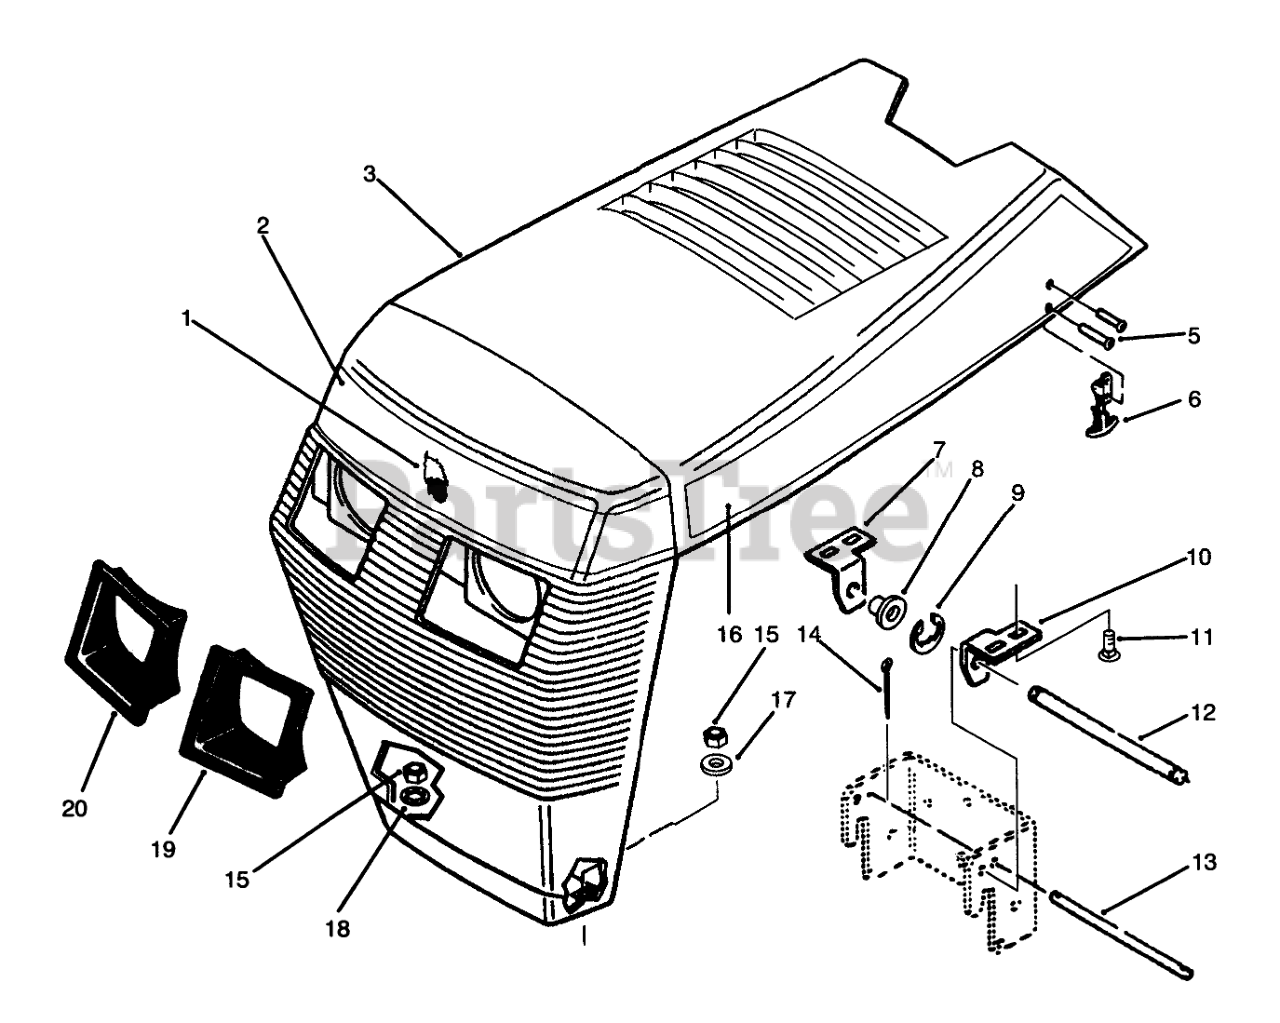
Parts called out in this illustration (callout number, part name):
1	PLATE - LOGO WHL HORSE
2	DECAL-FRONT HOOD, TOP
3	SERV.ASSY-HOOD & PKG
5	RIVET-POP
6	HANDLE ASM
7	BRACKET-GRILL, R H
8	BUSHING-NYLINER
9	RING-RETAINING
10	BRACKET-GRILL, LH
11	SCREW-CARR
12	ROD-GRILL PIVOT
13	ROD-HOOD STOP
14	PIN-COTTER
15	NUT-LOCK, NI
16	DECAL - LH HOOD TOP
17	WASHER-FLAT
18	WASHER-LOCK, INTERNAL
19	BEZEL-HEADLIGHT, LH
20	BEZEL-HEADLIGHT, RH
